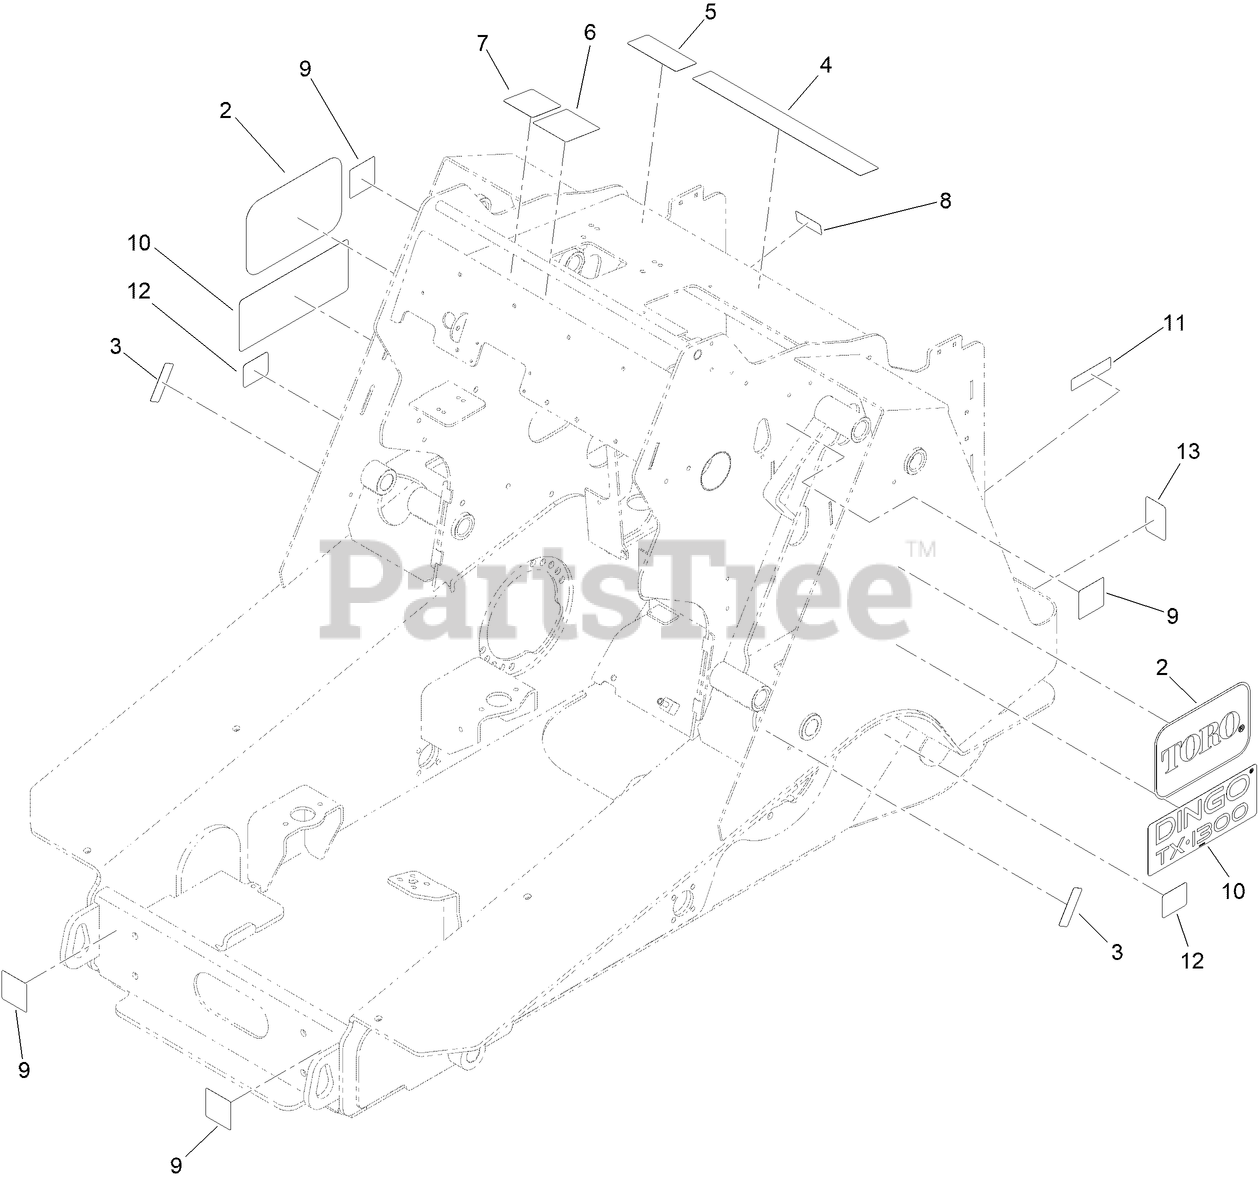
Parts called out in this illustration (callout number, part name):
2	DECAL
3	DECAL-WARNING, PINCH POINT
4	DECAL-SAFETY
5	DECAL-EXTENDED ARM SAFETY
6	DECAL-CONTROL, LOADER
7	DECAL-JOYSTICK CONTROLS
8	DECAL-SURFACE, HOT
9	DECAL-LIFT HERE
10	DECAL-DINGO TX1300
11	DECAL-ARRESTOR, SPARK
12	DECAL-TIE DOWN
13	REFLECTOR
